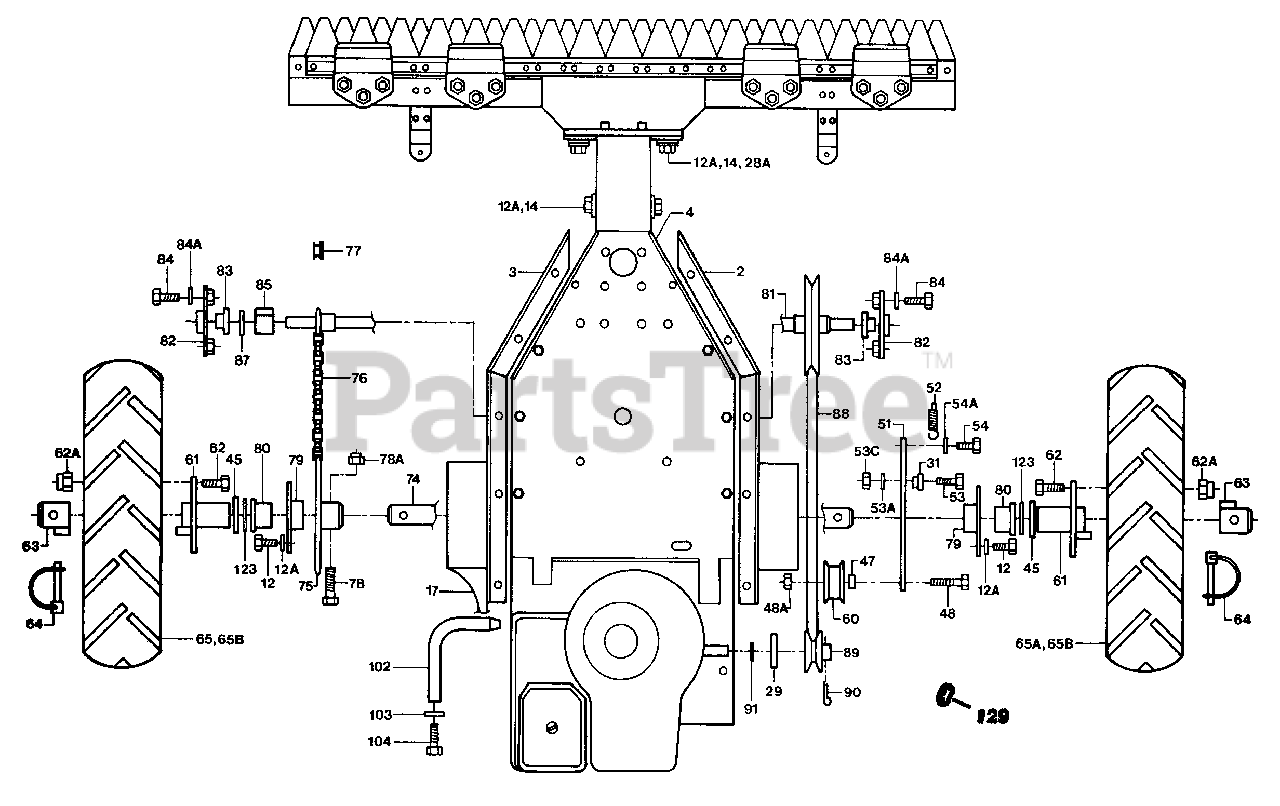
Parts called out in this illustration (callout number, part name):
2	Frame Plate-RIght
3	Frame Plate-Left
4	Frame Plate-Bottom
12	Screw-HHM8 x 12
12A	Washer
14	Screw-HHM8 x 16 Grade 10.9
17	Grass Shield-Wheel-LH
28A	Washer
29	Belt Guide
31	Clutch Plate Bushing
39	Retaining Clip-M8 x 40
45	Snap Ring
47	Spacer-Pulley
48	Screw-HHM12 x 40
48A	Nylon Nut
51	Clutch Plate
52	Spring-Clutch Plate
53	Screw-HHM10 x 35
53B	Nut-HM10
53C	Nut-Nylon-HM10
54	THIS REF. NO. NOT USED
54A	THIS REF. NO. NOT USED
61	Wheel Hub
62A	Lug Nut
63	Three-way Hub Lock
64	Retaining Clip (An extra included)
65	Wheel and Tire LH
65A	Wheel and Tire RH
74	Wheel Axle
75	Sprocket-Wheel Axle
76	Chain & Master Link
77	Master Link
78	Screw-HHM8 x 45
78A	Nylon Nut
79	Flange w/Bushing-Axle
80	Bushing-Wheel Axle
81	Jack Shaft Kit
82	Flange-Bearing Shaft
83	Bushing-Shaft
84	Screw-HHM6 x 12
84A	Washer
85	Spacer-Flange
86	Screw-HHM6 x 25
88	V-Belt-Wheel Drive
89	Pulley-Eng. Driven
90	Cotter Pin
91	Washer-Felt
102	Tube-Oil Drain
103	Washer-Copper
104	Screw-HHM12 x 18
123	Washer-Wheel
125	Grease Gun
129	Wheel Spacer
